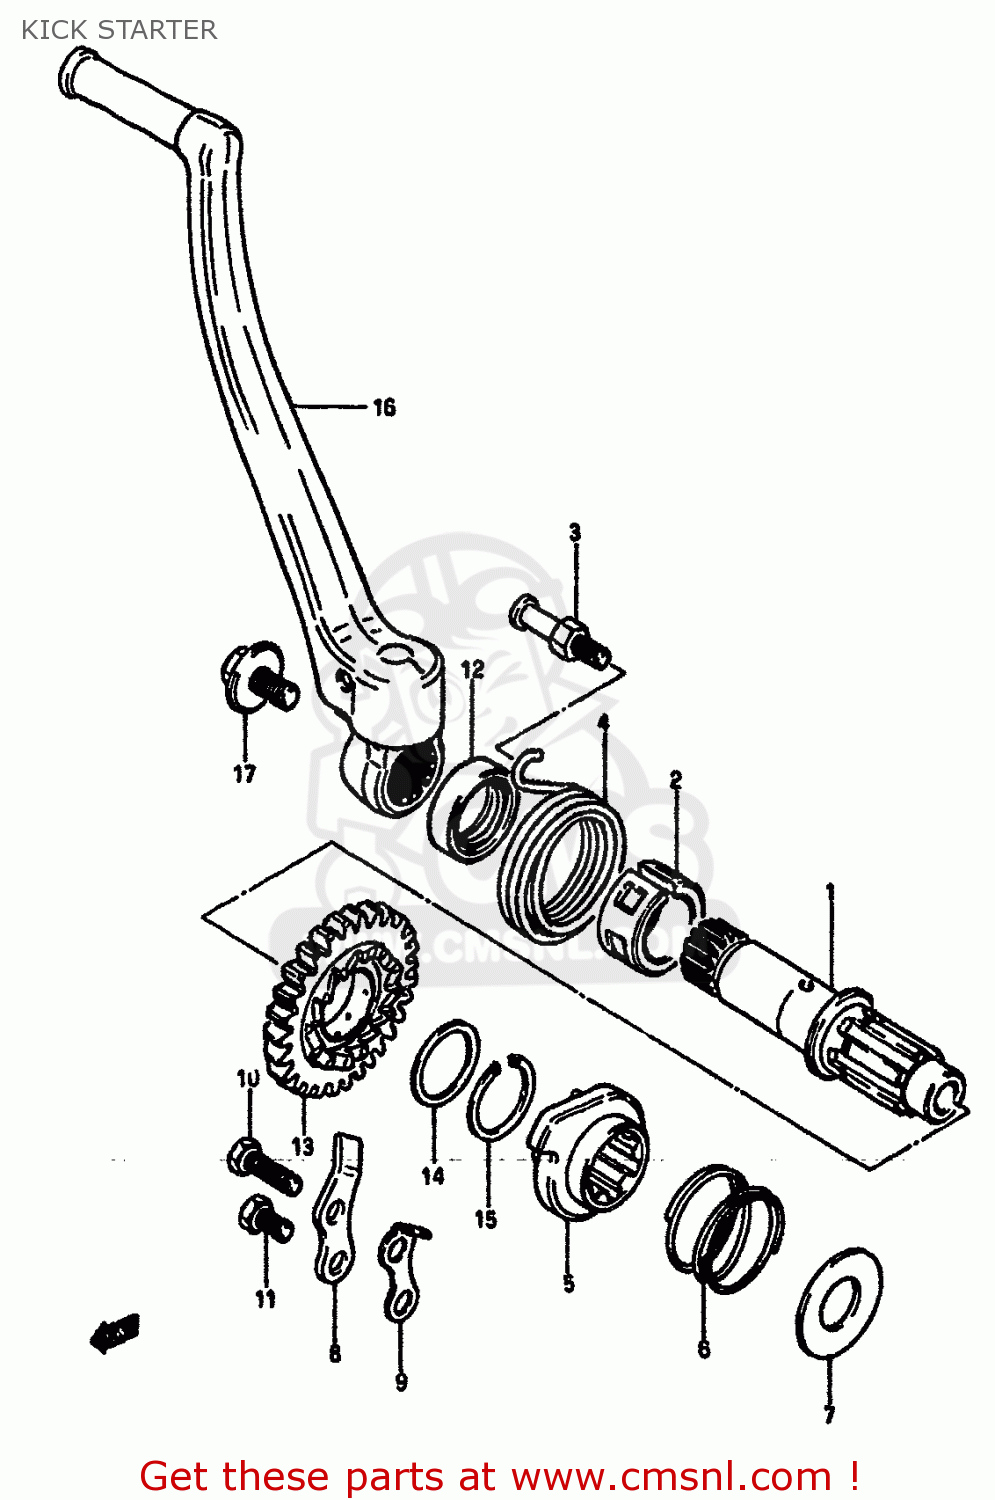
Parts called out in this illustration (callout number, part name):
1	SHAFT,KICK STARTER
2	GUIDE,KICK SHAFT SPRING
3	BOLT,KICK SHAFT SPRING
4	SPRING
5	STARTER,KICK
6	SPRING
7	WASHER
8	GUIDE,KICK STARTER
9	STOPPER,KICK STARTER
10	BOLT, UPPER
11	BOLT
12	SEAL,OIL(20X27X5)
13	GEAR,KICK STARTER DRIVE
14	SHIM
15	CIRCLIP
16	LEVER ASSEMBLY,KICK STARTER
17	BOLT(8X14)
